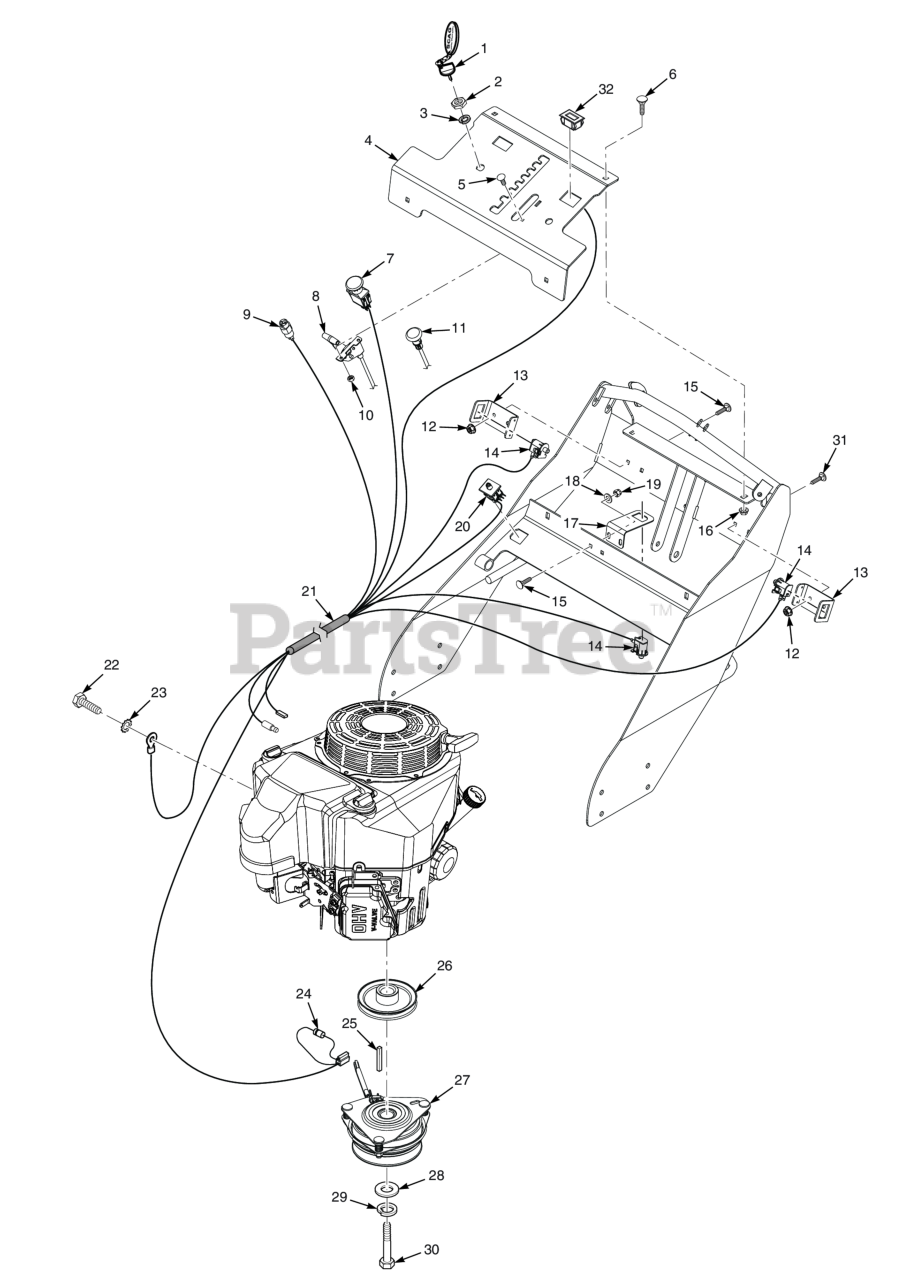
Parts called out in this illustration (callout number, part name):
1	Key, Assembly w/Fob
2	Nut, 5/8-32 Special
3	LOCK WASHER, 5/8" INTERNAL TOOTH
4	Instrument Panel w/Decal
5	Bolt, Carriage #10-24 x 1/2"
6	Bolt, 5/16-18 x .75 RHSN Carriage
7	Switch, PTO - 10 Amp
8	Throttle Cable
9	KEY SWITCH, MANUAL SRT.(INCL. HWD)
10	Nut, Elastic Stop #10-24
11	Choke Control
12	NUT, 1/4-20 SERRATED FLANGE HEX HEAD
13	Bracket, Operator Presence Switch
14	SWITCH, NEUTRAL INTERLOCK
15	Serr. Fl. Hex Head CPSCR, 1/4-20 x 3/4"
16	Nut, Serrated Flange 5/16-18 (Right Front Engine Mounting, Briggs and Kohler Only)
17	Bracket, Neutral Switch (Manual Start)
18	Flatwasher, 5/16-.375 x .875 x .083 (35BV & 37BV-EFI)
19	HEX, NUT, ELASTIC STOP LOCK, 1/4-20
20	Switch, Double Pole - Plunger
21	Wire Harness
22	Bolt, Hex Hd. M8-1.25 x 14mm
23	Lockwasher, 5/16" Ext. Tooth (Kohler x1)
24	Diode, 600V 6 Amp
25	KEY, 1/4 X 1/4 X 2-1/2"
26	Pulley, 4-1/2" Dia. - 1" Bore
27	Electric Clutch Assembly
28	Flatwasher, 7/16-.469 x 1.75 x .25 (48, 52)
29	Lockwasher, 7/16� Spring
30	Bolt, Hex Head 7/16-20 x 3" w/t Patch
31	Bolt, Carriage, 1/4-20 x 1-1/4"
32	Hour Meter, Inductive
